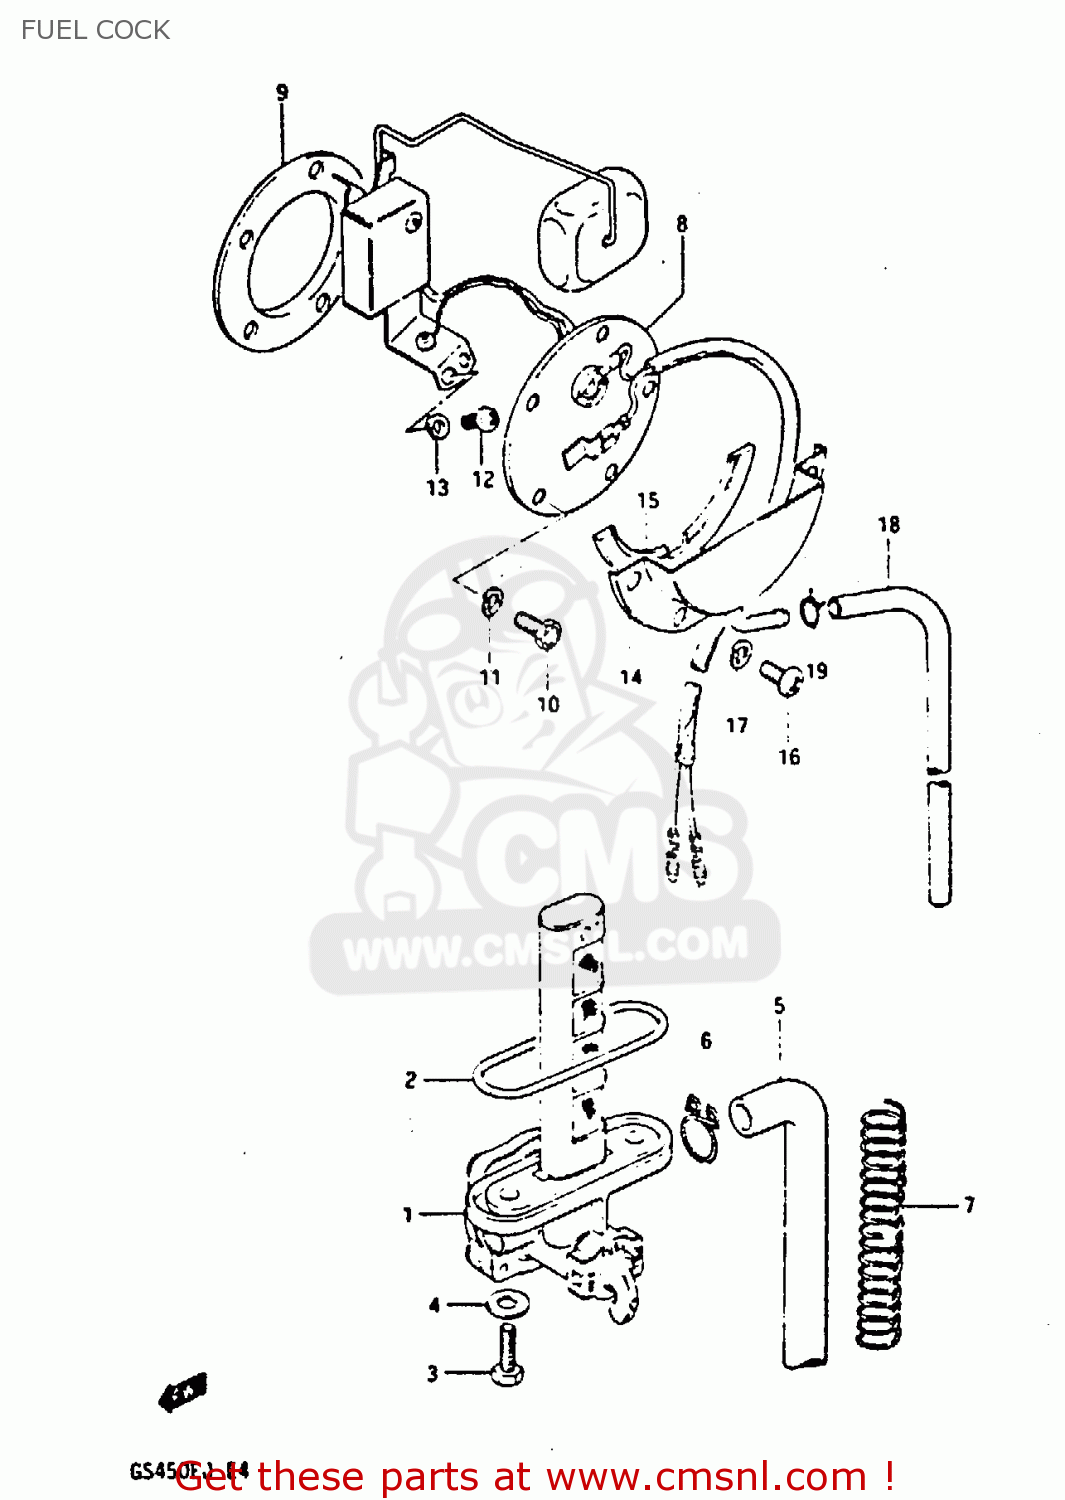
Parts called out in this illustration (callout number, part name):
1	COCK ASSY,FUEL
2	O RING
3	BOLT(6X20)
4	GASKET
5	HOSE
6	CLIP
7	SPRING
8	GUAGE, FUEL LEVEL
9	GASKET,FUEL LEVEL GAUGE (NAS)
10	BOLT
11	LOCK WASHER
12	SCREW 5X10
13	LOCK WASHER
14	PLATE,FUEL DRAIN
15	GASKET (NAS)
16	SCREW
17	LOCK WASHER
18	HOSE
19	CLIP
